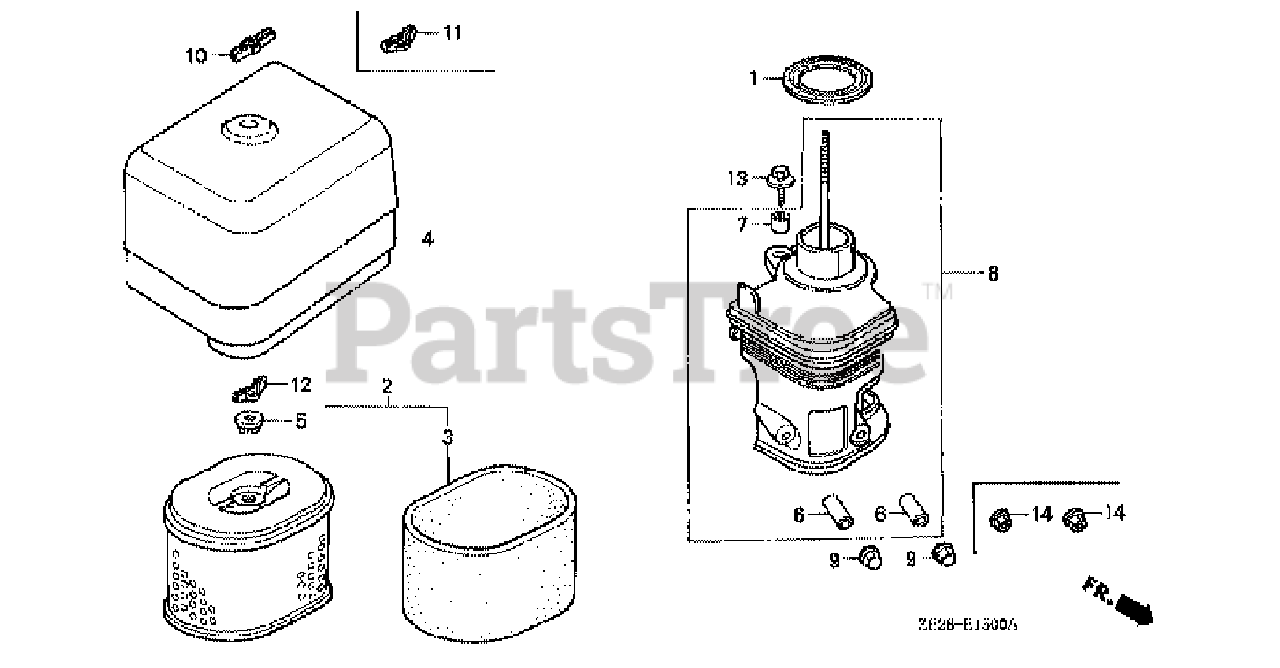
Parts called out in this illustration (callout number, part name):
1	GASKET, ELBOW
2	ELEMENT, AIR CLEANER (DUAL)
3	FILTER (OUTER)
4	COVER, AIR CLEANER
5	GROMMET, AIR CLEANER
6	COLLAR, AIR CLEANER
7	COLLAR B, AIR CLEANER
8	ELBOW, AIR CLEANER
9	NUT, CAP (6MM)
10	WINGNUT, AIR CLEANER COVER
10	WINGNUT (6MM)
12	WINGNUT, TOOL BOX SETTING
13	BOLT-WASHER (6X20)
14	NUT, FLANGE (6MM)
